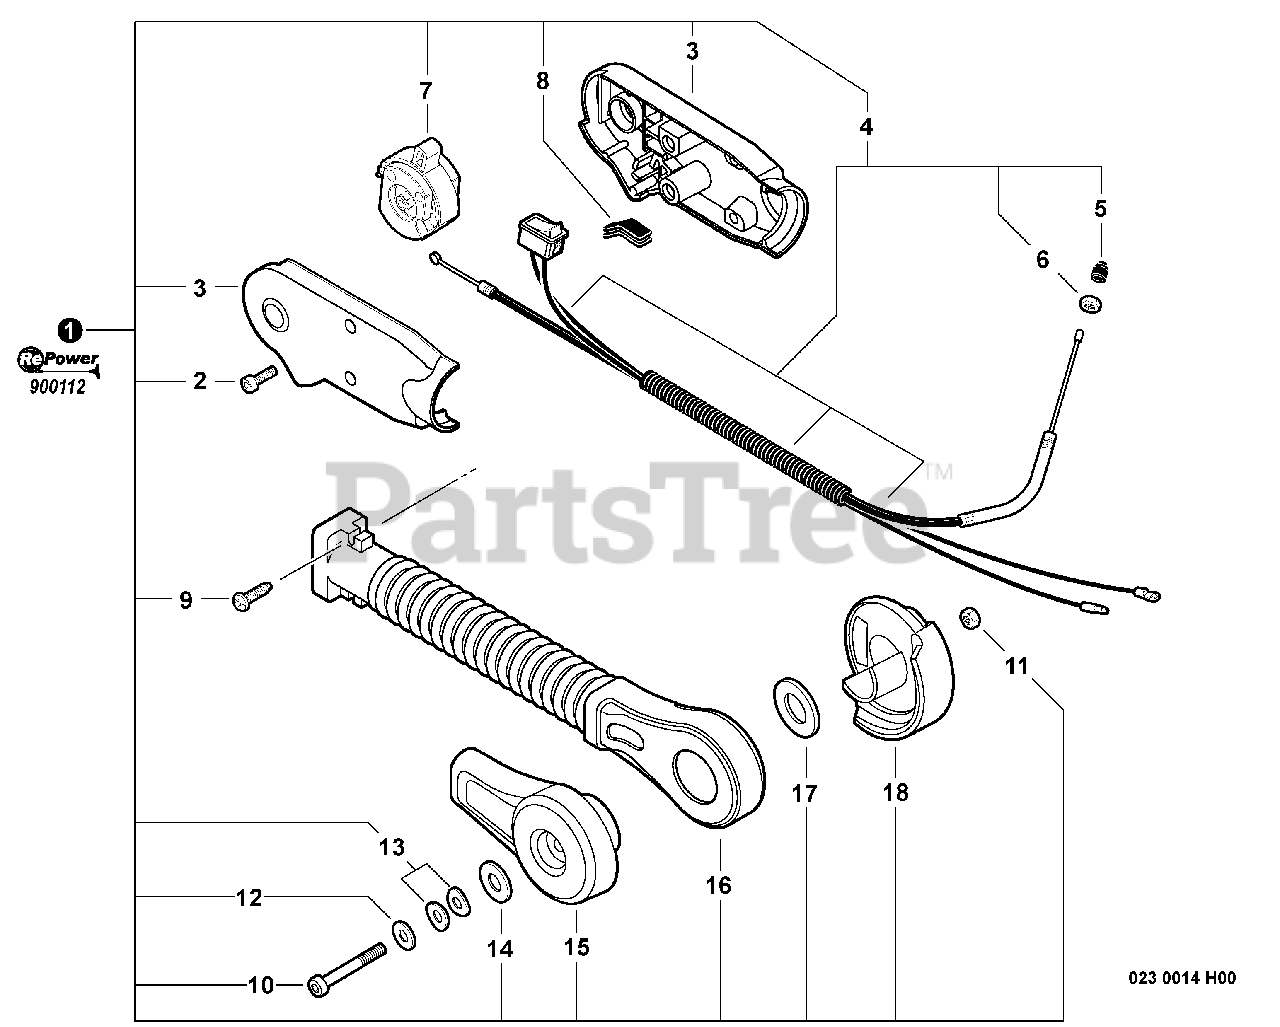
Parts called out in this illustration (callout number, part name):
1	HIP MOUNT THROTTLE CONTROL KIT
2	SCREW - 5X16
3	CONTROL HANDLE KIT
4	CONTROL CABLE ASSY
5	CAP, DUST
6	LOCKNUT - 6
7	THROTTLE CONTROL ASSY
9	SCREW - 5X20
10	SCREW - 6X75
11	LOCKNUT - 6
12	WASHER - 6
13	WASHER - SPRING
14	WASHER - 6
15	BRACKET, ARM - OUTER
16	ARM, THROTTLE CONTROL
18	BRACKET, ARM - INNER
